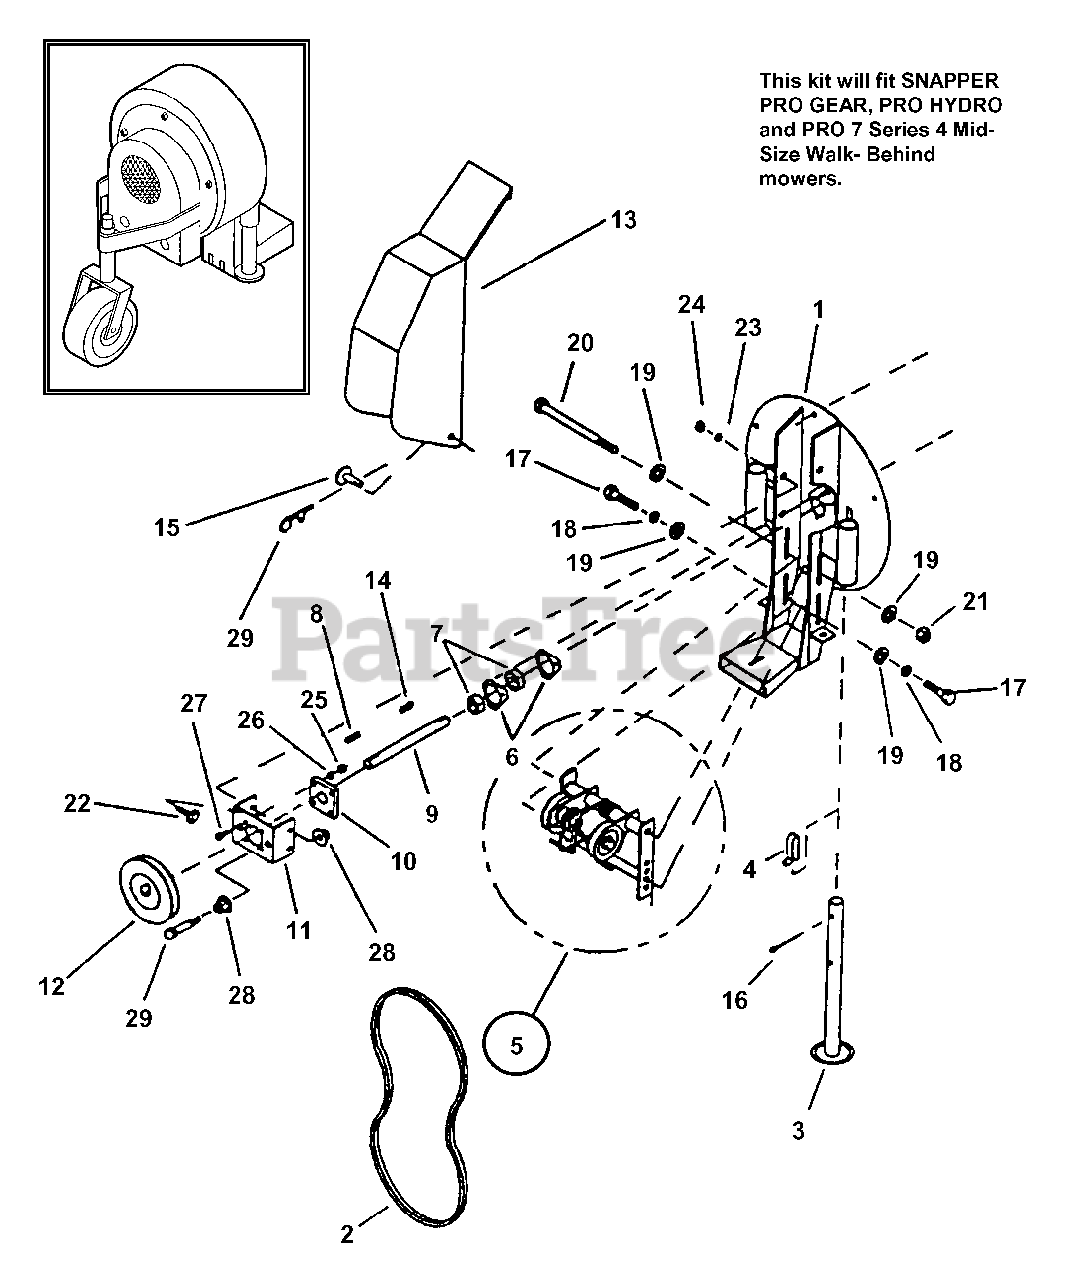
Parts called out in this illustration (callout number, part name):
1	HOUSING
2	BELT, SP Models with Kohler Engine
3	STAND, Parking
4	SNAP BUTTON
5	ASSEMBLY, Idler
6	FLANGE, Bearing
7	BEARING with Locking Collar
8	KEY, 1/4" Square x 1" long
10	BEARING
11	BOX, Reduction
12	PULLEY, MB50
13	COVER, Belt
14	KEY, 1/4" Square x 2-1/2" long
15	COVER PIN, 1/4" Dia. x 1/2" long
16	PIN, 3/16" Dia. x 2" Cotter
17	BOLT, 3/8-16 x 1-1/4" Hex
18	WASHER, 3/8" Lock
19	WASHER, 7/16" Flat
20	BOLT, 3/8-16 x 8-1/2" Hex Head
21	NUT, 3/8-16 Hex
22	BOLT, 5/16-18 x 1" Square Neck Carriage
23	WASHER, 5/16" Lock
24	NUT, 5/16-18 Hex, Grade 5 or B
25	NUT, 7/16-14
26	WASHER, 7/16" Lock
27	BOLT, 7/16-14 x 1-1/4" Hex
28	NUT, 5/16-18 Hex Flange Lock, Grade 5 or B
